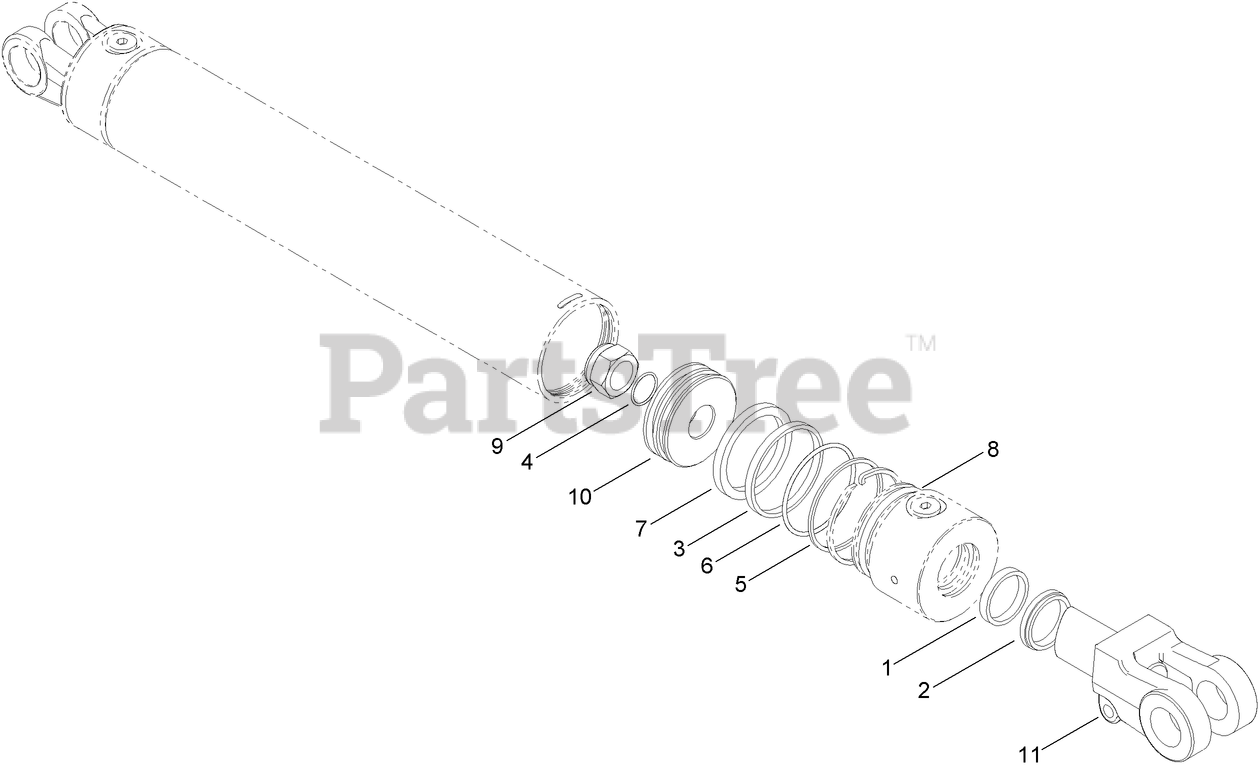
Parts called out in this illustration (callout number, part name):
1	SEAL-ROD
2	SEAL-WIPER
3	SEAL-Piston
4	O-RING
5	RING-BACKUP
6	O-RING
7	RING-WEAR, PISTON
8	O-RING
9	NUT-CYLINDER PISTON
10	PISTON
11	ROD-PISTON
